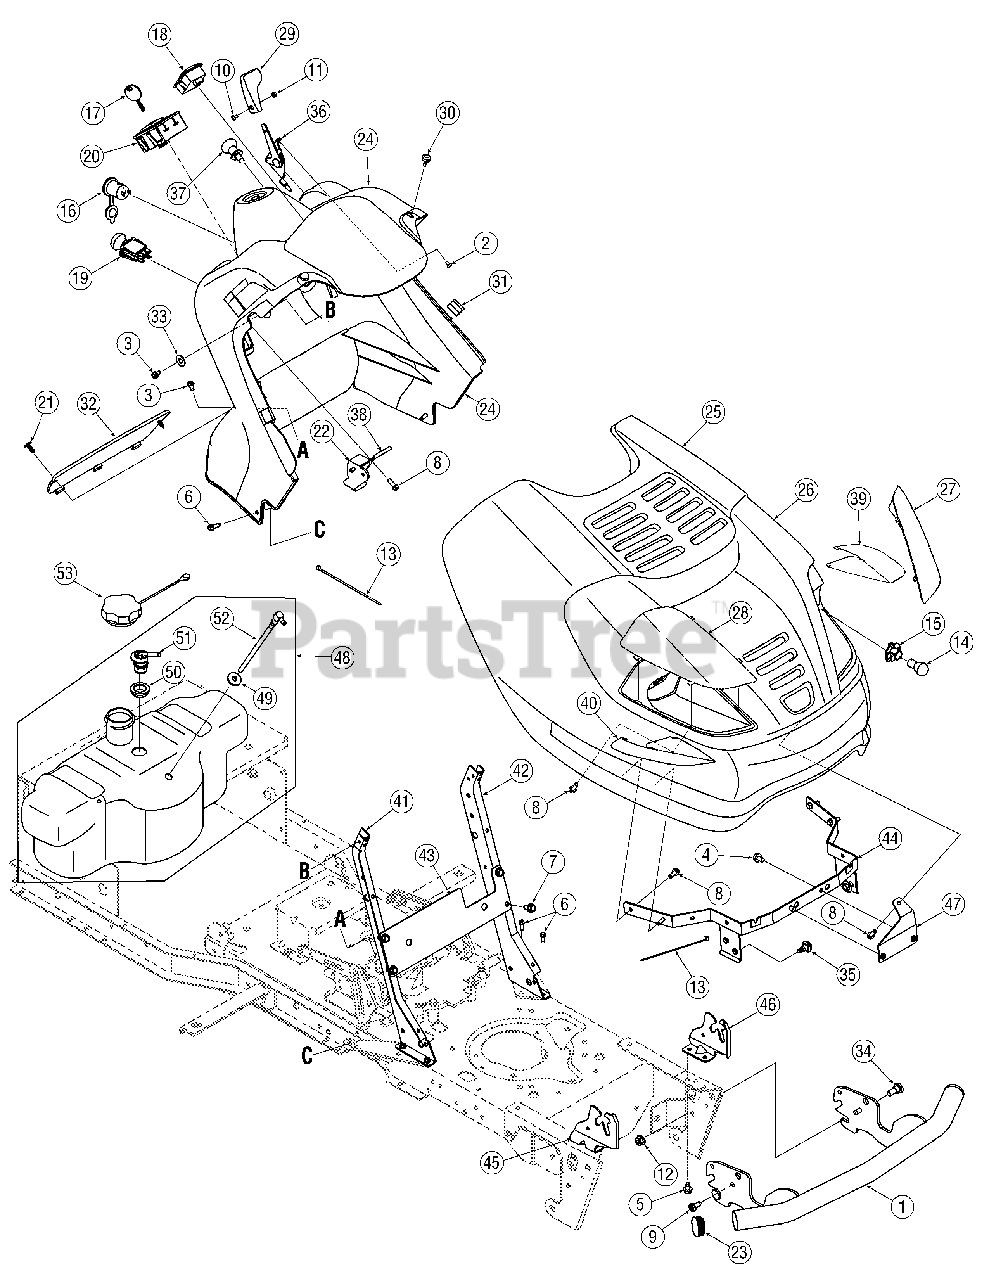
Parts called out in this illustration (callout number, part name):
2	Screw, Truss Hd. Mach., 10-24 x .375
3	Screw, Hex Wash Hd. Tapp, 1/4-20 x .5
4	Screw, Hex Wash Hd. Tapp, 5/16-18 x .625
5	Screw, Hex Wash Hd. Tapp, 5/16-18 x .5
6	Screw, Hex Wash Hd. Tapp, 1/4-20 x .75
7	Screw, Hex Wash Hd. Tapp, 5/16-12 x .75
8	Screw, Hex Wash Hd. Tapp, 1/4-15 x .75
9	Screw, Pan Hd. Tapp, 5/16-18 x .75
10	Screw, Truss Hd. Mach., #8-32 x .375
11	Nut, Hex, 8-32
12	Nut, Hex Flange Insert Lock, 3/8-16 GrF
13	Tie, Cable
14	Bulb, 12V Light
15	Receptacle, Light
16	Receptacle, 12V Power
17	Key, Ignition Switch
18	Meter, Indicator/Service Monitor
19	Switch, PTO
20	Switch, Ingition/Module
21	Clip, Ratchet
22	Lever, Dash Brake
23	Cap, Bumper
24	Panel, Dash
26	Plenum, Hood
27	Lense, Head Light LH
28	Lense, Head Light RH
29	Knob, Throttle Control
31	Deflector, Rubber Hood
32	Net, Storage
33	Washer, Flat, .25 x .63 x .0515
34	Bolt, Shoulder, .496 x .336:3/8-16
35	Screw, Shoulder, .43 x .29:TT5/16-18
36	Cable, Throttle Control
37	Cable, Choke Control
38	Rod, Brake Lock Pivot
39	Label, Reflector
40	Label, Reflector
49	Bushing, Fuel Tank
50	Grommet, Rubber
51	Valve, Rollover
52	Fitting, Fuel Pick Up
53	Cap, Fuel Tank
